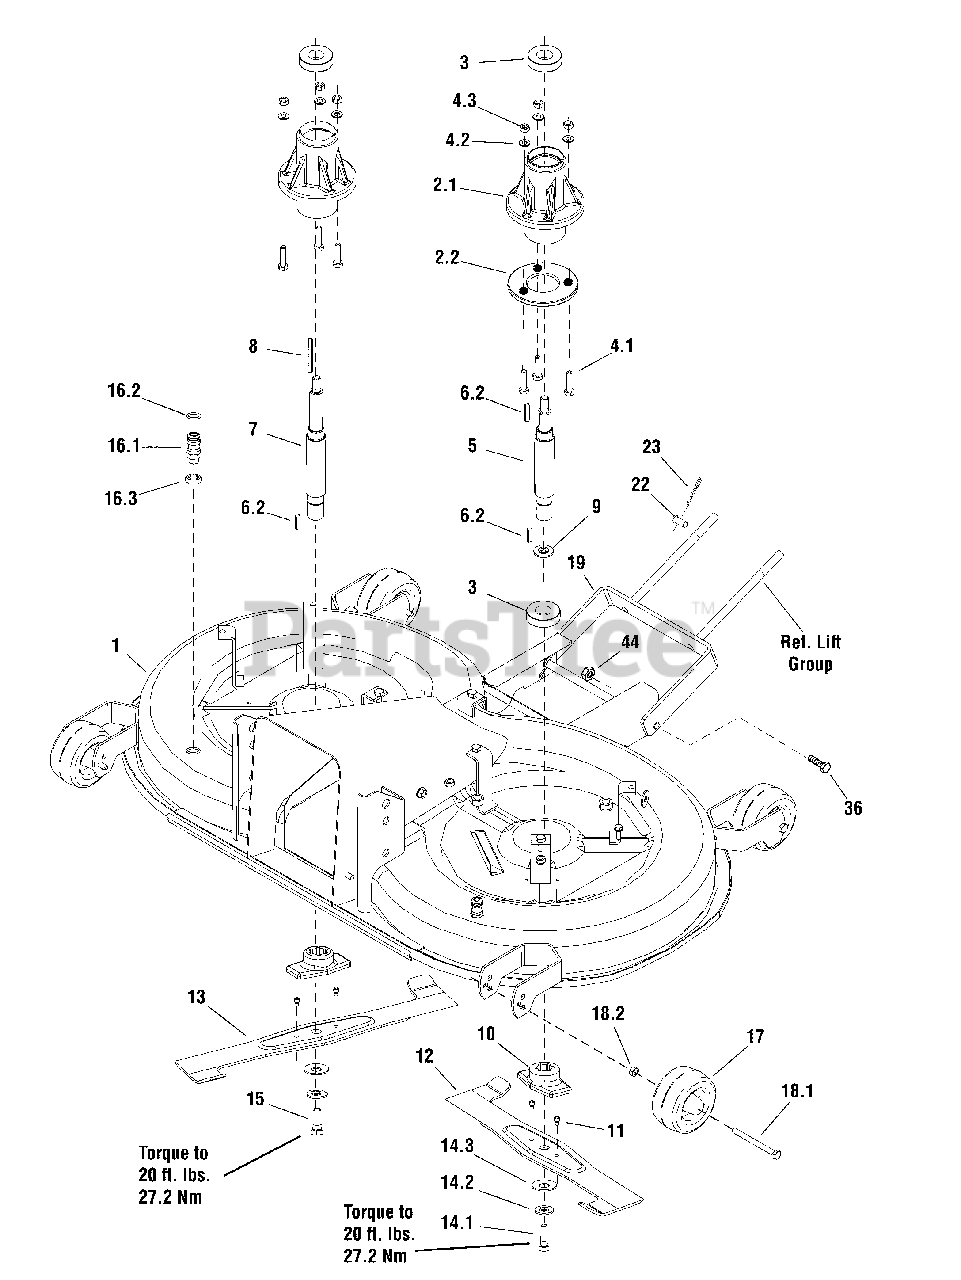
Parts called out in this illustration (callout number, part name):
1	COVER, Cutting Knife, Complete
2.1	HOUSING
2.2	REINFORCEMENT
3	BEARING, 6205 2 RS C 66IB
4.1	SCREW, M8 x 35
4.2	WASHER, 8.4
4.3	NUT, M8
4.3	NUT, Flange Lock, M8
6.2	TONGUE, 6 H 9 x 6 x 28
8	TONGUE, 6 H 9 x 6 x 63
9	RING, Safety, 25
10	HOUSING
11	SHEAR, STUD 0-9311-736
12	CUTTING KNIFE, Rotary, Right
13	CUTTING KNIFE, Rotary, Left
14.1	SCREW, 0-9011-287, M10
14.2	WASHER, 0-9220-749
14.3	WASHER, BN 806-40 x 16.3 x 2 x 3.1
15	SCREW, 0-9011-283 M10, Left Thread
16.1	QUICK FASTENER, 0-9026-246
16.2	RING, 13 x 2 NBR
16.3	NUT, M12
17	CUTTING WHEEL, Right ETOP 100-8,2
18.1	SCREW, M8 x 90
18.2	NUT, M8
19	HINGE, Front
22	MOWING STUD, 1-9310-290
23	PIN, Flexible, 0-9245-999
36	BOLT, M12 x 25
44	NUT, M12
